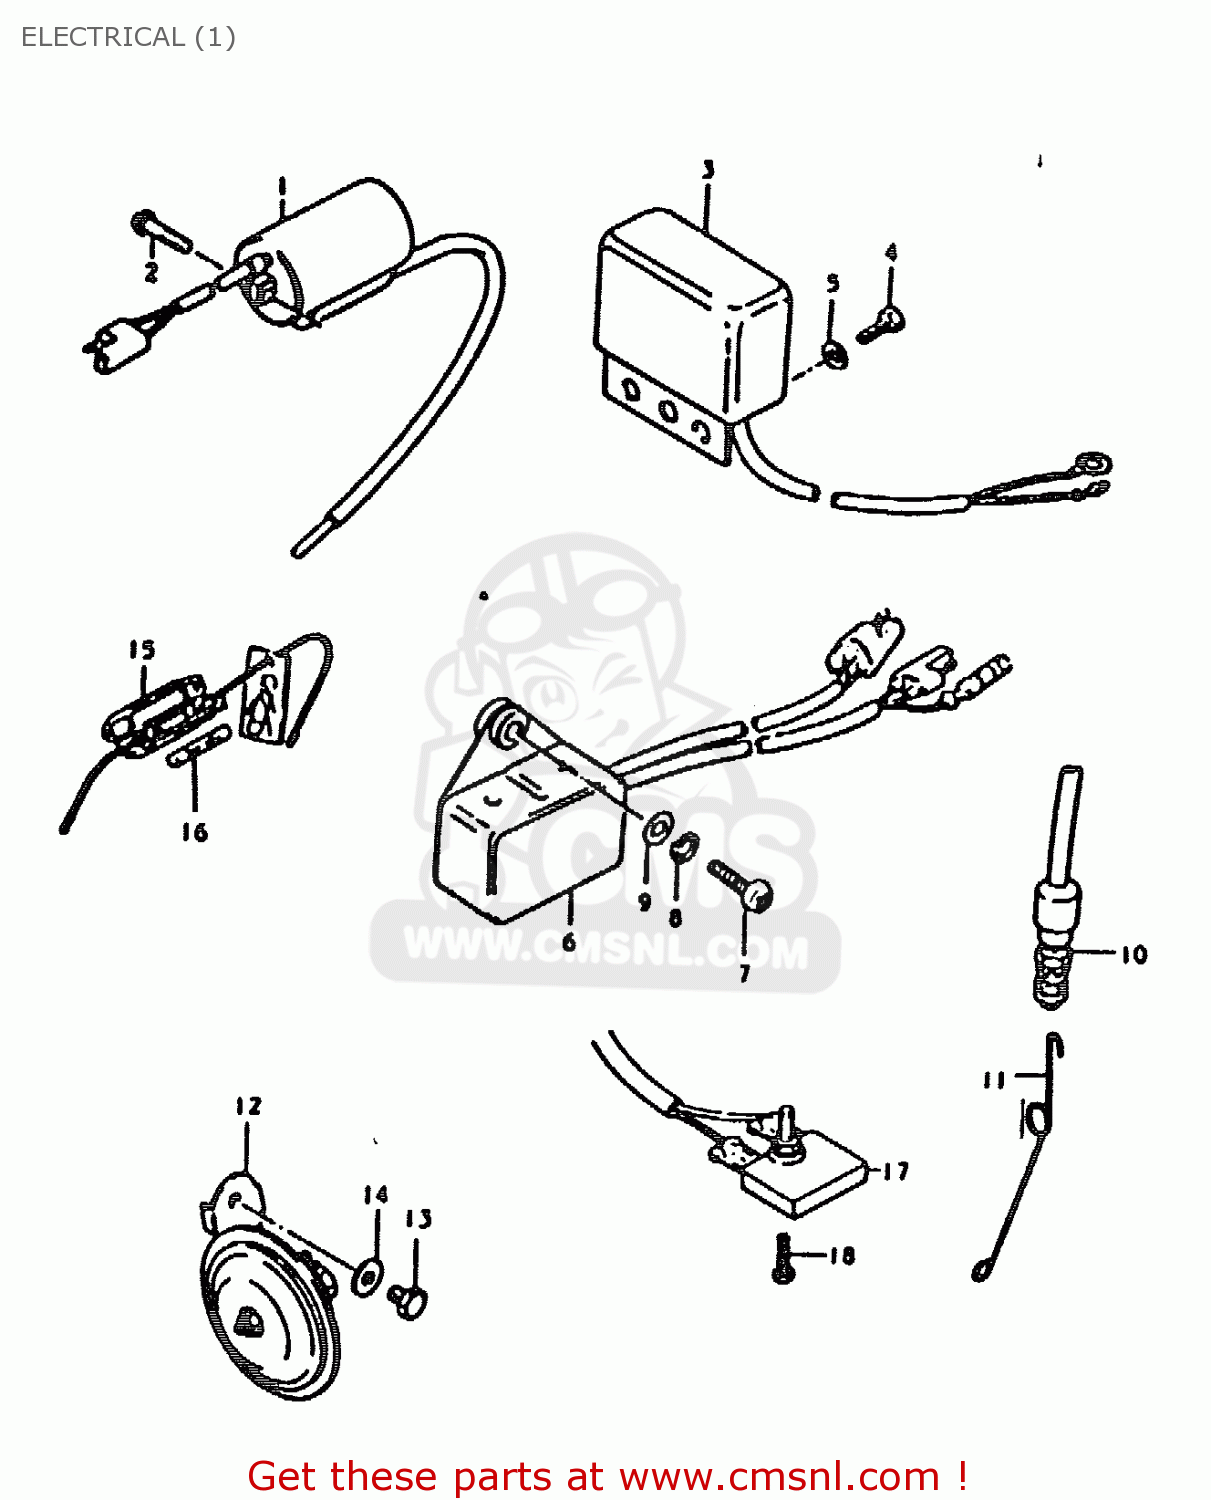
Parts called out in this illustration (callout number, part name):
1	COIL ASSEMBLY,IGNITION
2	SCREW 5X20
3	REGULATOR ASSEMBLY
4	SCREW(5X12)
5	WASHER
6	CDI UNIT
7	SCREW
8	LOCK WASHER
9	WASHER
10	SWITCH ASSEMBLY,STOP LAMP
11	SPRING
12	HORN ASSEMBLY
13	BOLT
14	WASHER
15	BOX ASSEMBLY,FUSE
16	FUSE(15A)
17	RECTIFIER ASSEMBLY
18	SCREW
